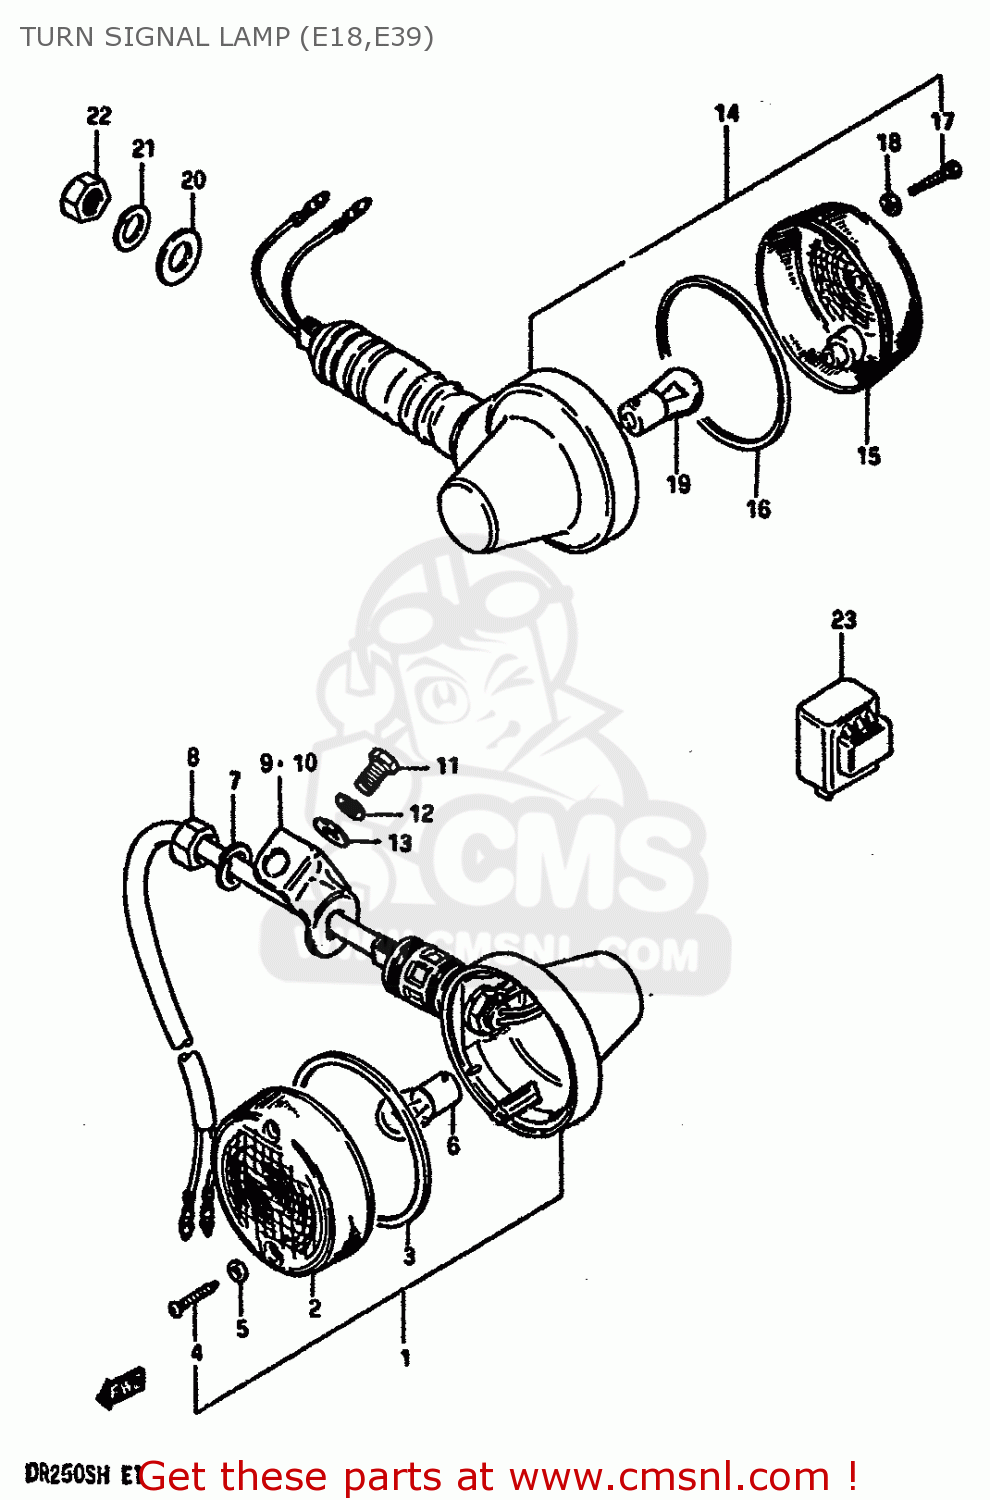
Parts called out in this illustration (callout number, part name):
1	LAMP,FRONT TURN SIGNAL
2	LENS
3	GASKET (NAS)
4	SCREW TAPP.
5	GASKET (NAS)
6	BULB(12V21W)
7	WASHER,LOCK 12
8	NUT
9	BRACKET,TURNSIGNAL LAMP,R
10	BRACKET,TURNSIGNAL LAMP,L
11	BOLT
12	WASHER,LOCK
13	WASHER
14	LAMP,REAR TURN SIGNAL
15	LENS
16	GASKET (NAS)
17	SCREW TAPP.
18	GASKET (NAS)
19	BULB(12V21W)
20	WASHER
21	LOCK WASHER
22	NUT
23	RELAY ASSEMBLY,TURN SIGNAL
